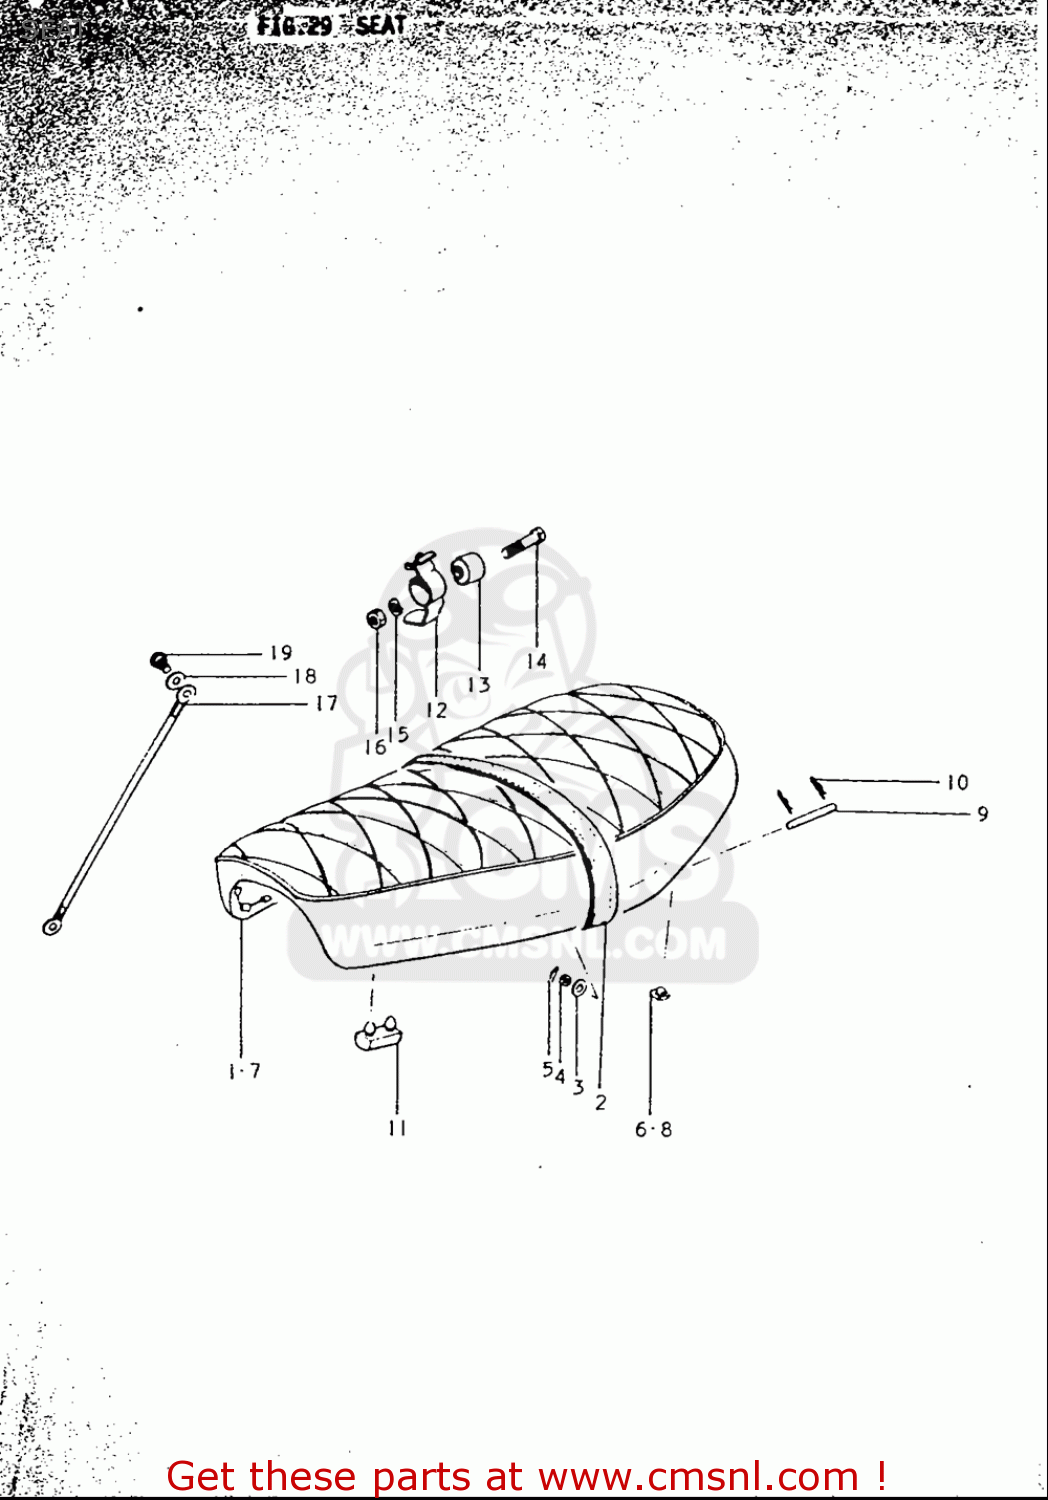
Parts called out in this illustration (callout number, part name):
3	WASHER
4	NUT
5	CLIP
6	CUSHION
8	CUSHION
10	CLIP
11	CUSHION
13	BUSHING
14	BOLT
15	WASHER,LOCK
16	NUT
18	WASHER
